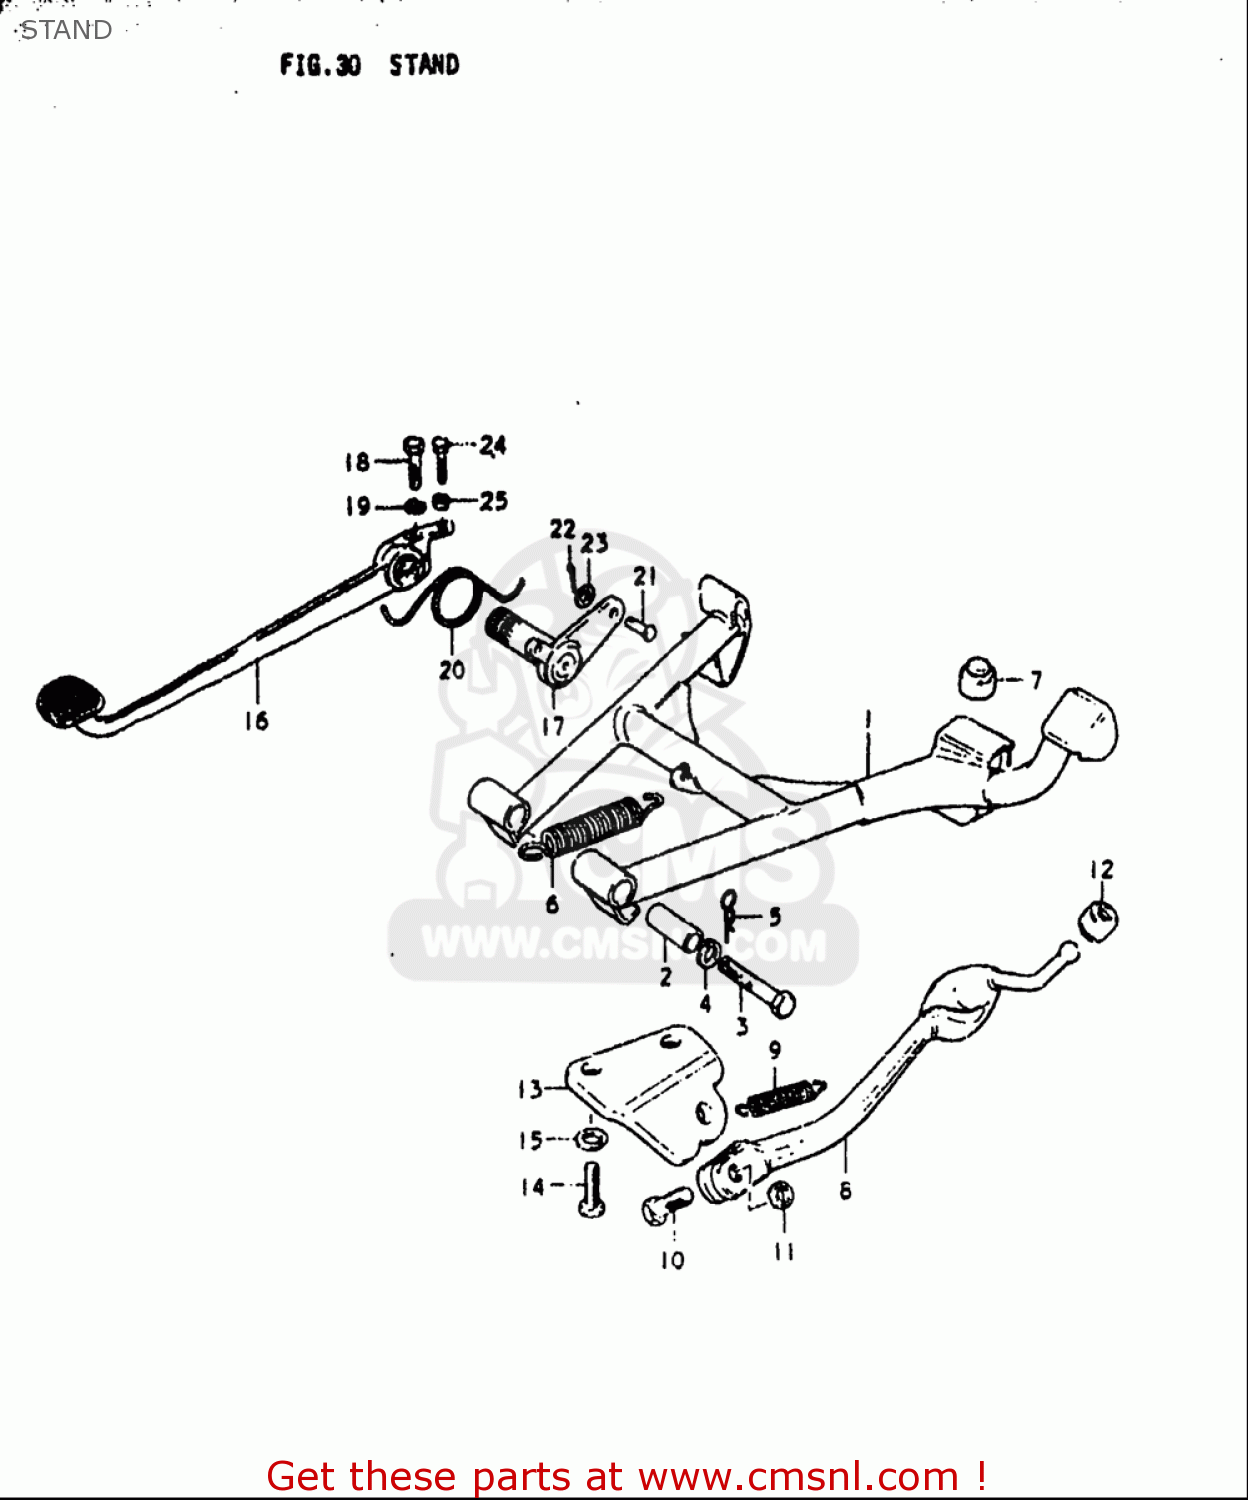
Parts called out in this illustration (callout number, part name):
2	SPACER(10X16X38.8)
3	BOLT(10X65)
4	WASHER,LOCK
5	CLIP
6	SPRING
7	CUSHION
8	STAND,PROP
9	SPRING
10	BOLT(10X30)
11	NUT
12	CUSHION
14	BOLT(10X27)
15	WASHER,LOCK
18	BOLT
19	WASHER,LOCK
20	SPRING
21	PIN
22	PIN
23	WASHER
24	BOLT
25	NUT
